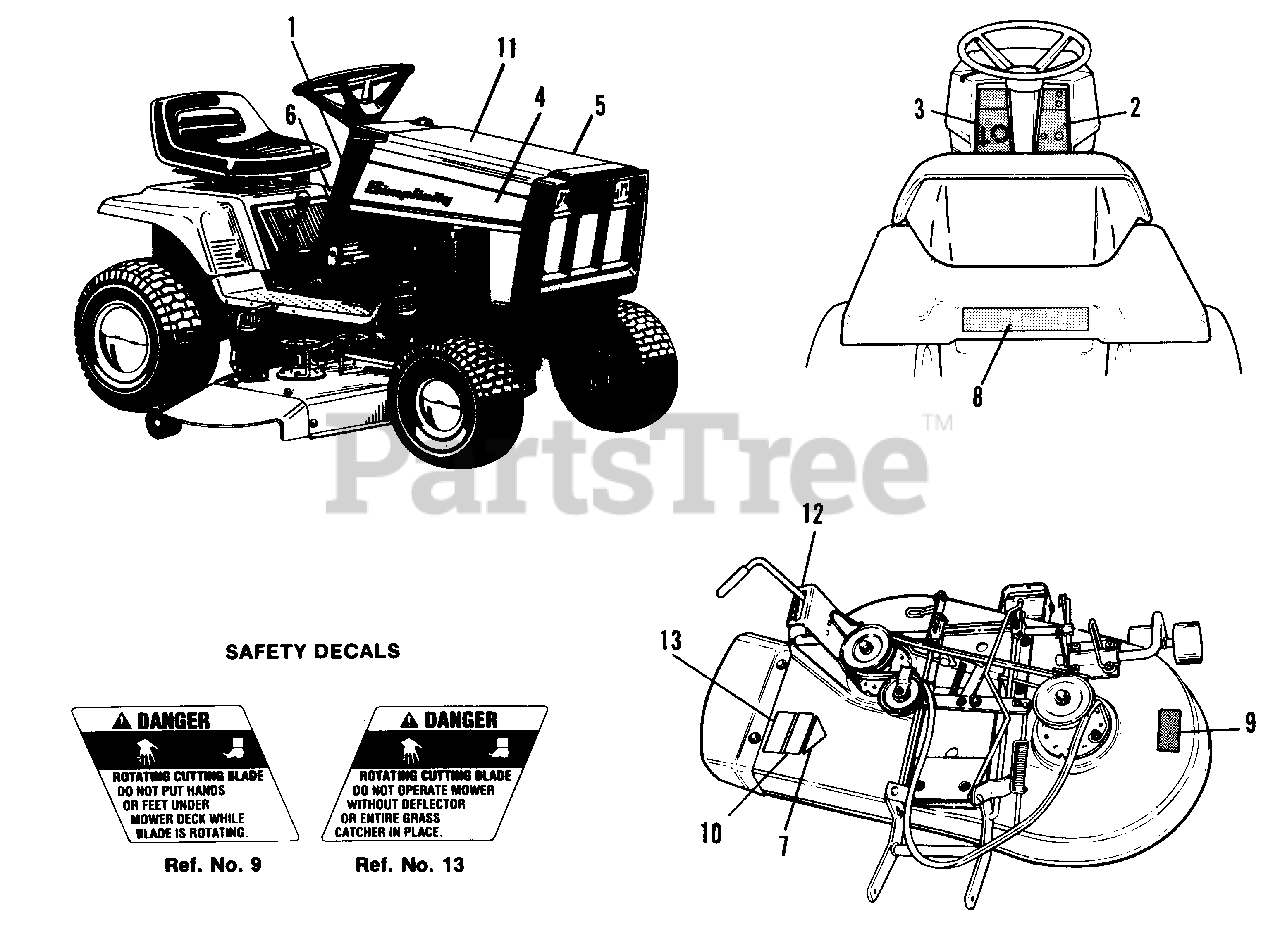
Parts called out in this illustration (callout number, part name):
1	DECAL, Shift Pattern
2	DECAL, Dash, R.H.
3	DECAL, Dash, L.H.
4	DECAL, Hood, R.H.
5	DECAL, Hood, L.H.
6	DECAL, 12LTH
7	DECAL, OPEI
8	DECAL, Simplicity
9	DECAL, Danger, Rotating Blade
10	DECAL, Cutting Width, 36"
11	DECAL, Drive Belt
12	DECAL, Mower Height
13	DECAL, Danger, Deflector In Place
